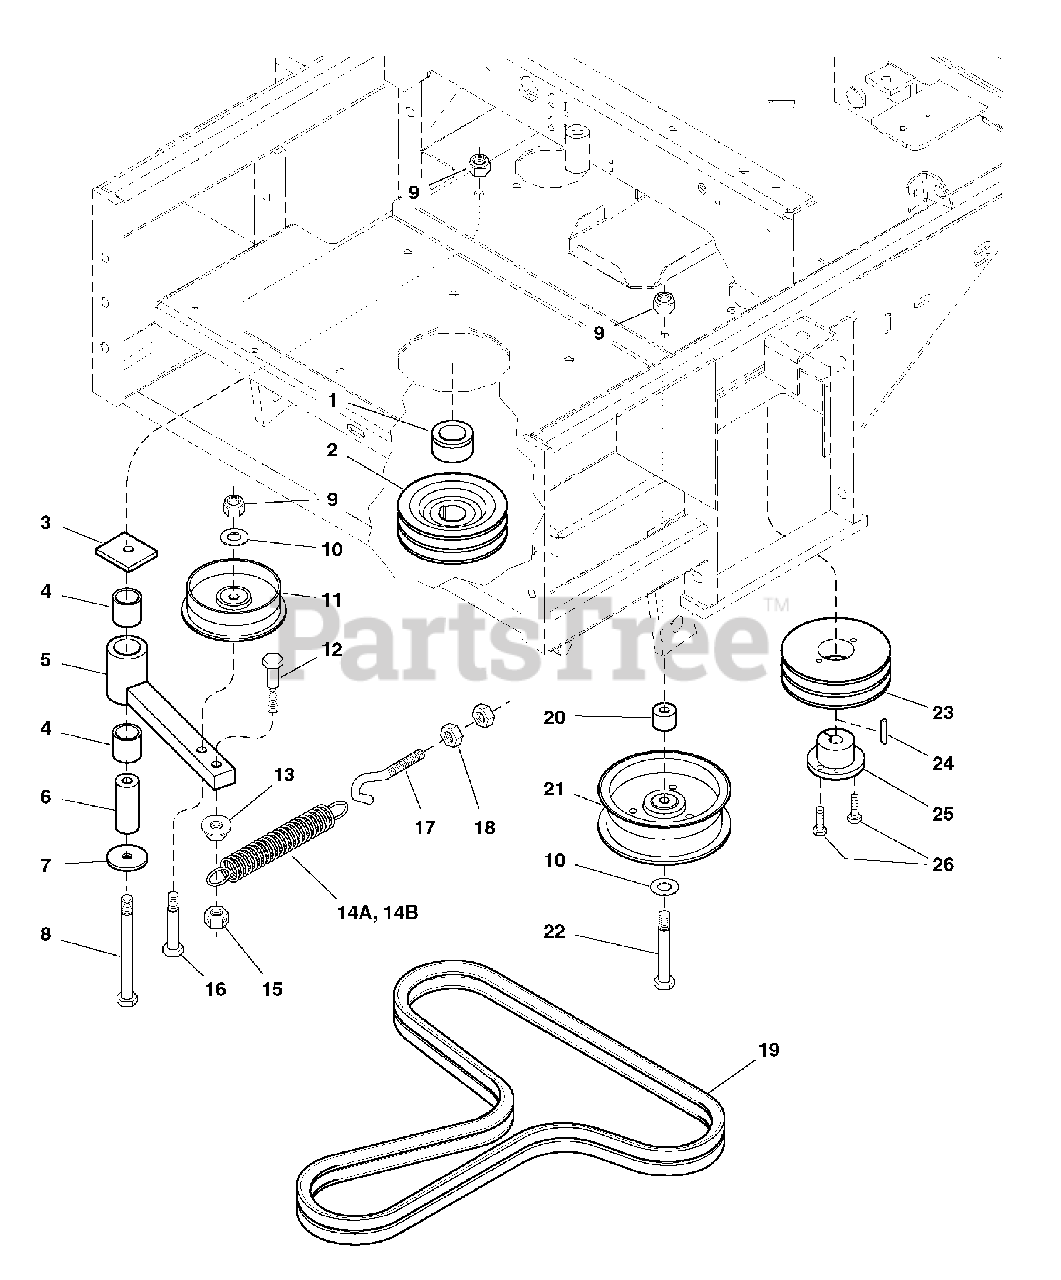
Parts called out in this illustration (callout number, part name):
1	CRANKSHAFT SPACER
2	CRANKSHAFT PULLEY
3	SPACER, Idler Pivot
4	BUSHING, Brass
5	PUMP DRIVE IDLER ARM
6	SHAFT, Idler Pivot
7	RETAINER, Idler Arm
8	CAPSCREW, Hex Hd, 3/8-16 x 4
9	NUT, Hex, Nylon Lock, 3/8-16
10	WASHER, 3/8
11	PULLEY, Idler (Single Flange)
12	CAPSCREW, Hex Hd, 3/8-16 x 1-3/4
13	NUT, Hex, Serrated Flange, 3/8-16
14A	SPRING, Extension (S/N 101-810)
14B	SPRING, Extension, Swivel End (S/N 811 & up)
15	NUT, Hex, Side Lock, 3/8-16
16	CAPSCREW, Hex Hd, 3/8-16 x 2-1/4
17	SCREW HOOK, 3/8-16 x 4-1/4
18	NUT, Hex, 3/8-16
19	BELT, BANDED A-SEC, 64.76EL, POLY, RAW EDGE
20	SPACER, Idler
21	PULLEY, Idler
22	CAPSCREW, Hex Hd, 3/8-16 x 2-3/4
23	PULLEY, Pump Drive
24	KEY, 5mm x 25mm
25	BUSHING, Tapered Hub
26	BOLT, 1/4-20 X 1", GD
